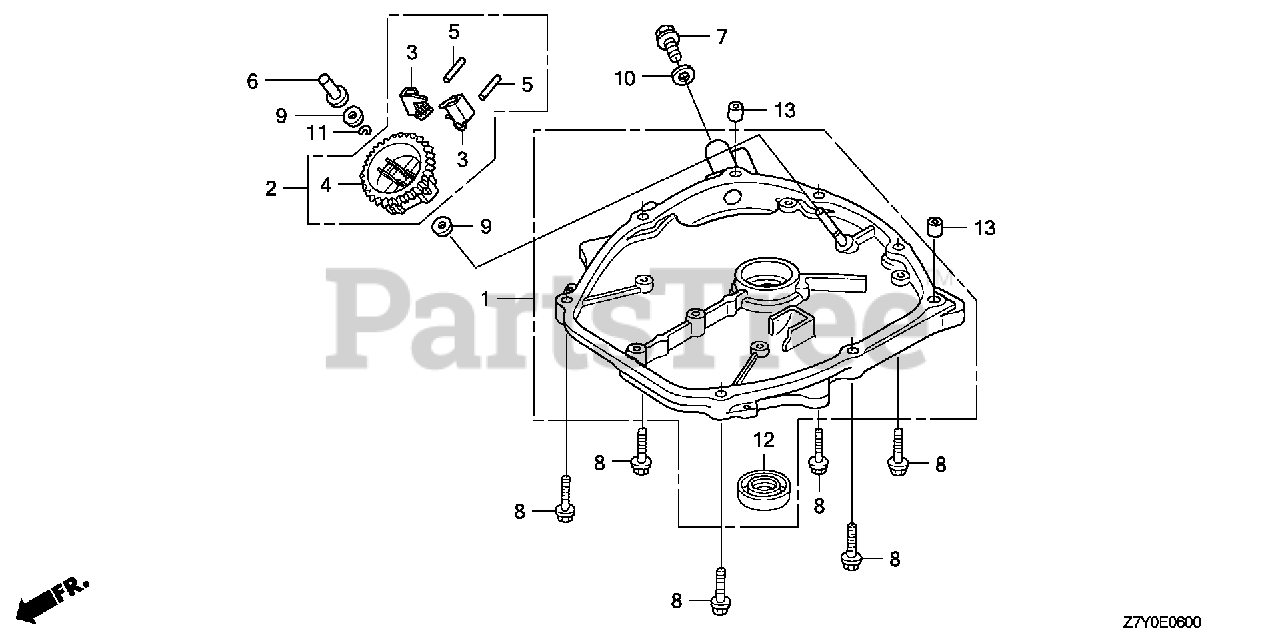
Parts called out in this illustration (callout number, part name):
1	COVER, CRANKCASE SIDE
2	GOVERNOR ASSY.
3	WEIGHT, GOVERNOR
4	HOLDER, GOVERNOR WEIGHT
5	PIN, GOVERNOR WEIGHT
6	SLIDER, GOVERNOR
7	BOLT, PLUG DRAIN (12MM)
8	BOLT, FLANGE (5X23)
9	WASHER (4.2X13)
10	WASHER, DRAIN PLUG (12MM)
11	CLIP, GOVERNOR HOLDER
12	OIL SEAL (18.9X28X5) (ARAI)
13	PIN, DOWEL (6X10)
